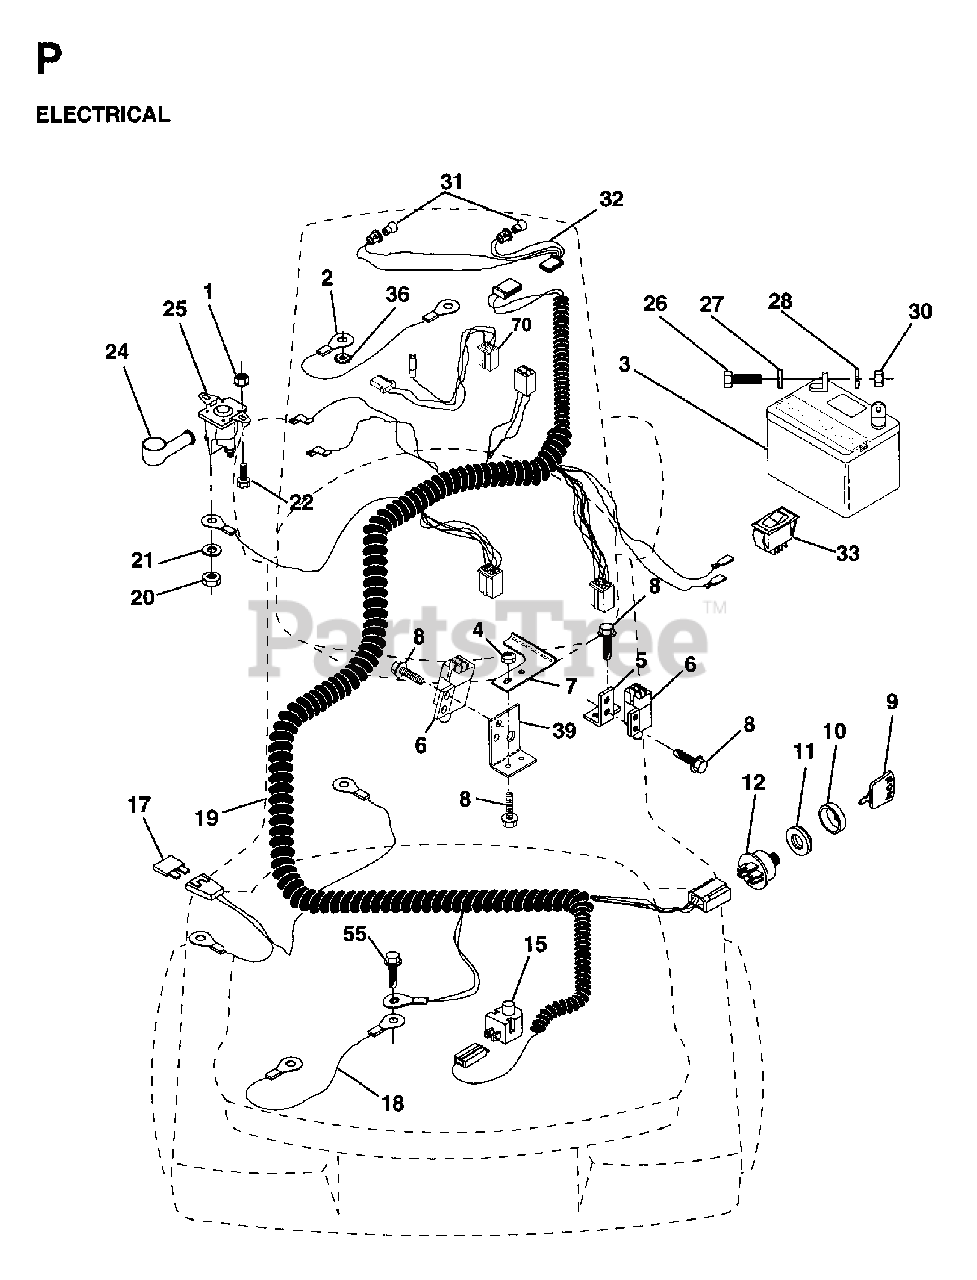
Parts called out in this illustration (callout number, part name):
2	CABLE ASM
3	BATTERY.DRY.30.AMP
5	BRACKET LT
6	SWITCH INTERLOCKT
7	KEEPER, ACTUAT. L.R.
9	KEY MLD GEN DELTA
10	COVER SWITCH KEY
11	NUT, IGNITION
12	IGNITION SWITCH
15	SWITCH SEAT
19	HARNESS IGN LR NLA
20	NUT
21	LOCKWASHER
24	TERMINAL COVER
25	SOLINOID
27	WASHER
28	LOCKWASHER
30	NUT
31	LIGHTBULB
32	HARNESS LIGHT SOCKET
33	SWITCH LT
36	LOCKWASHER
70	HARNESS, ENGINE
